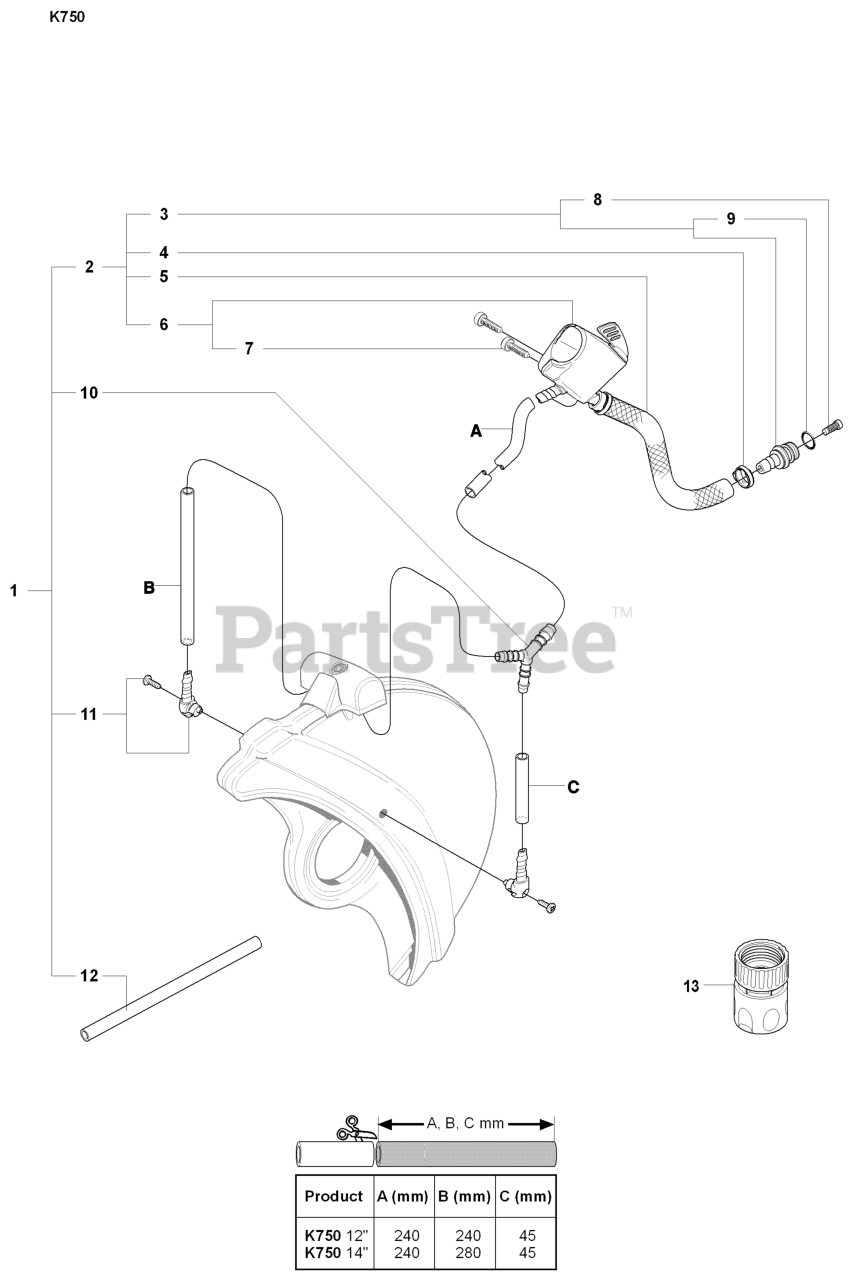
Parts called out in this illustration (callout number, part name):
1	WATER HOSE KIT
2	RP HOSE
3	NIPPLE
4	RP CLAMP
5	%HOSE
6	VALVE ASSY
8	FILTER
9	RP O-RING
12	RP HOSE 800MM
13	FEMALE HOSE CONNECTOR
